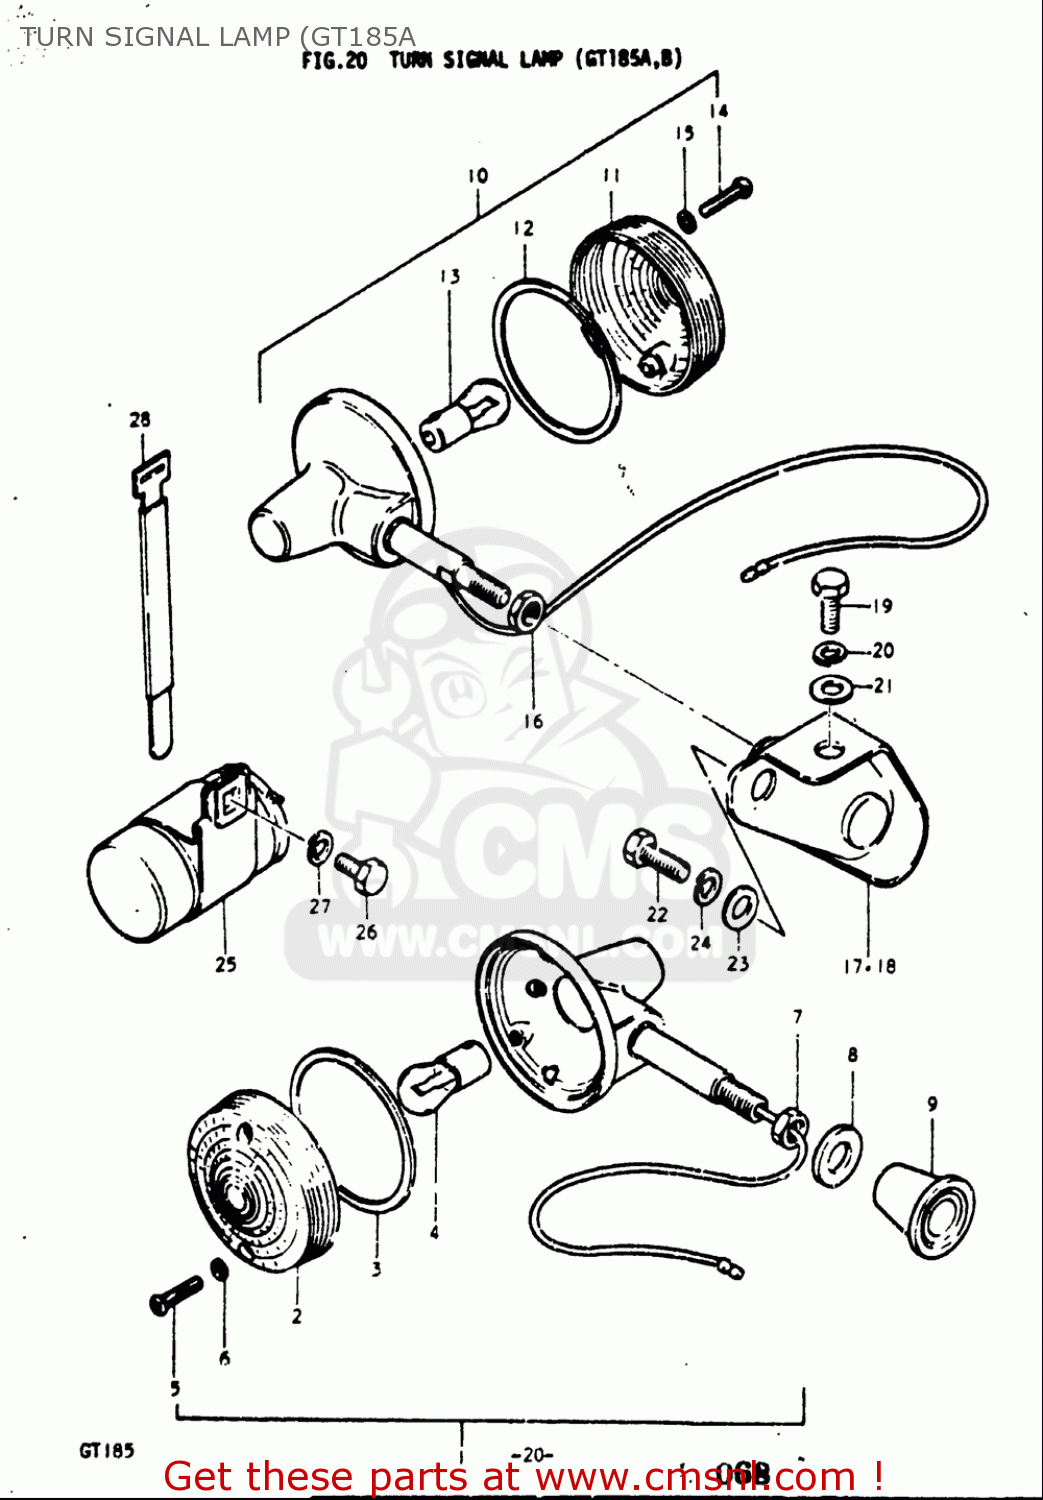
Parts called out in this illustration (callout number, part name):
2	LENS
3	GASKET (NAS)
4	BULB(12V23W,STANLEY,A4577A)
6	GASKET (NAS)
7	NUT
8	WASHER
9	COVER,FRONT TURN SIGNAL BRACKET
10	LAMP ASSY,RR TURNSIGNAL
11	LENS
12	GASKET (NAS)
13	BULB(12V23W,STANLEY,A4577A)
15	GASKET (NAS)
16	NUT
19	BOLT
20	WASHER,LOCK
21	WASHER
22	BOLT
23	WASHER
24	WASHER,LOCK
25	RELAY ASSY,TURNSIGNAL
26	BOLT
27	WASHER
28	CLAMP
